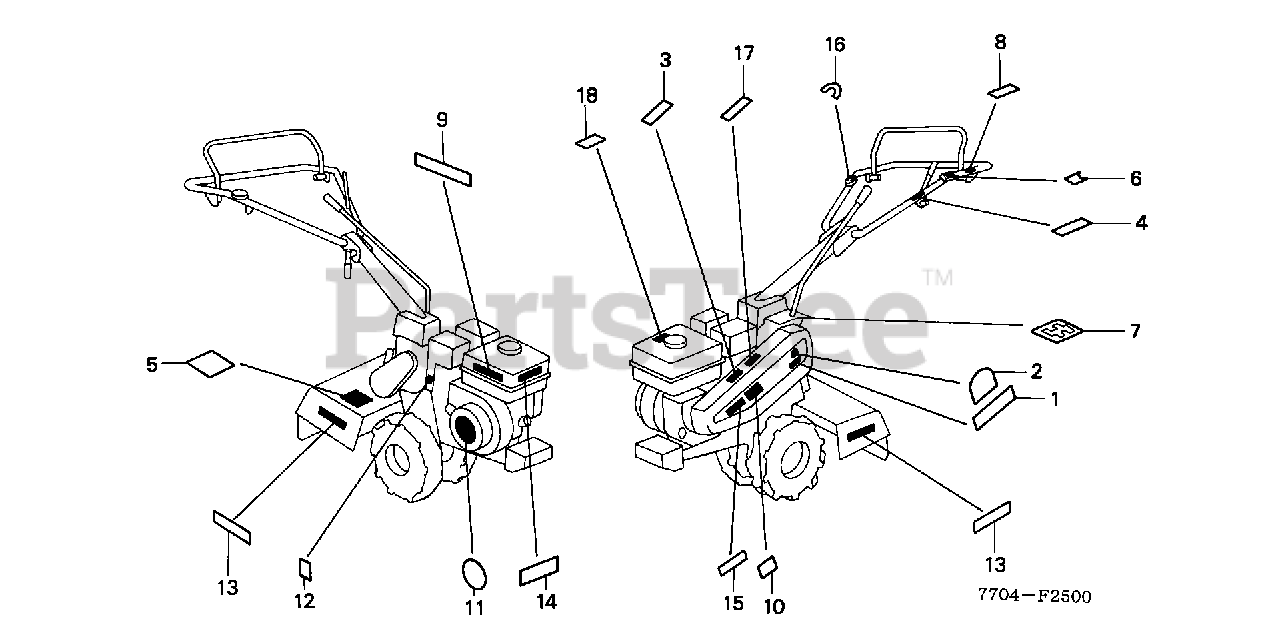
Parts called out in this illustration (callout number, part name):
1	MARK, L. STRIPE (FR600)
2	MARK, SIDE EMBLEM
3	LABEL, BELT WARNING (ENGLISH)
4	MARK, TINE CLUTCH INDICATION
5	LABEL, TINE DANGER (ENGLISH)
6	MARK, ENGINE SWITCH INDICATION (ENGLISH)
7	MARK, CHANGE
8	MARK, MAIN CLUTCH INDICATION
9	LABEL, OPERATOR WARNING
11	PLATE, EMBLEM
12	MARK, CHOKE
13	MARK, HONDA EMBLEM (160)
14	MARK, HONDA EMBLEM (12 (HONDA)
15	EMBLEM (13 (HONDA)
17	LABEL, HEAT WARNING (ENGLISH)
